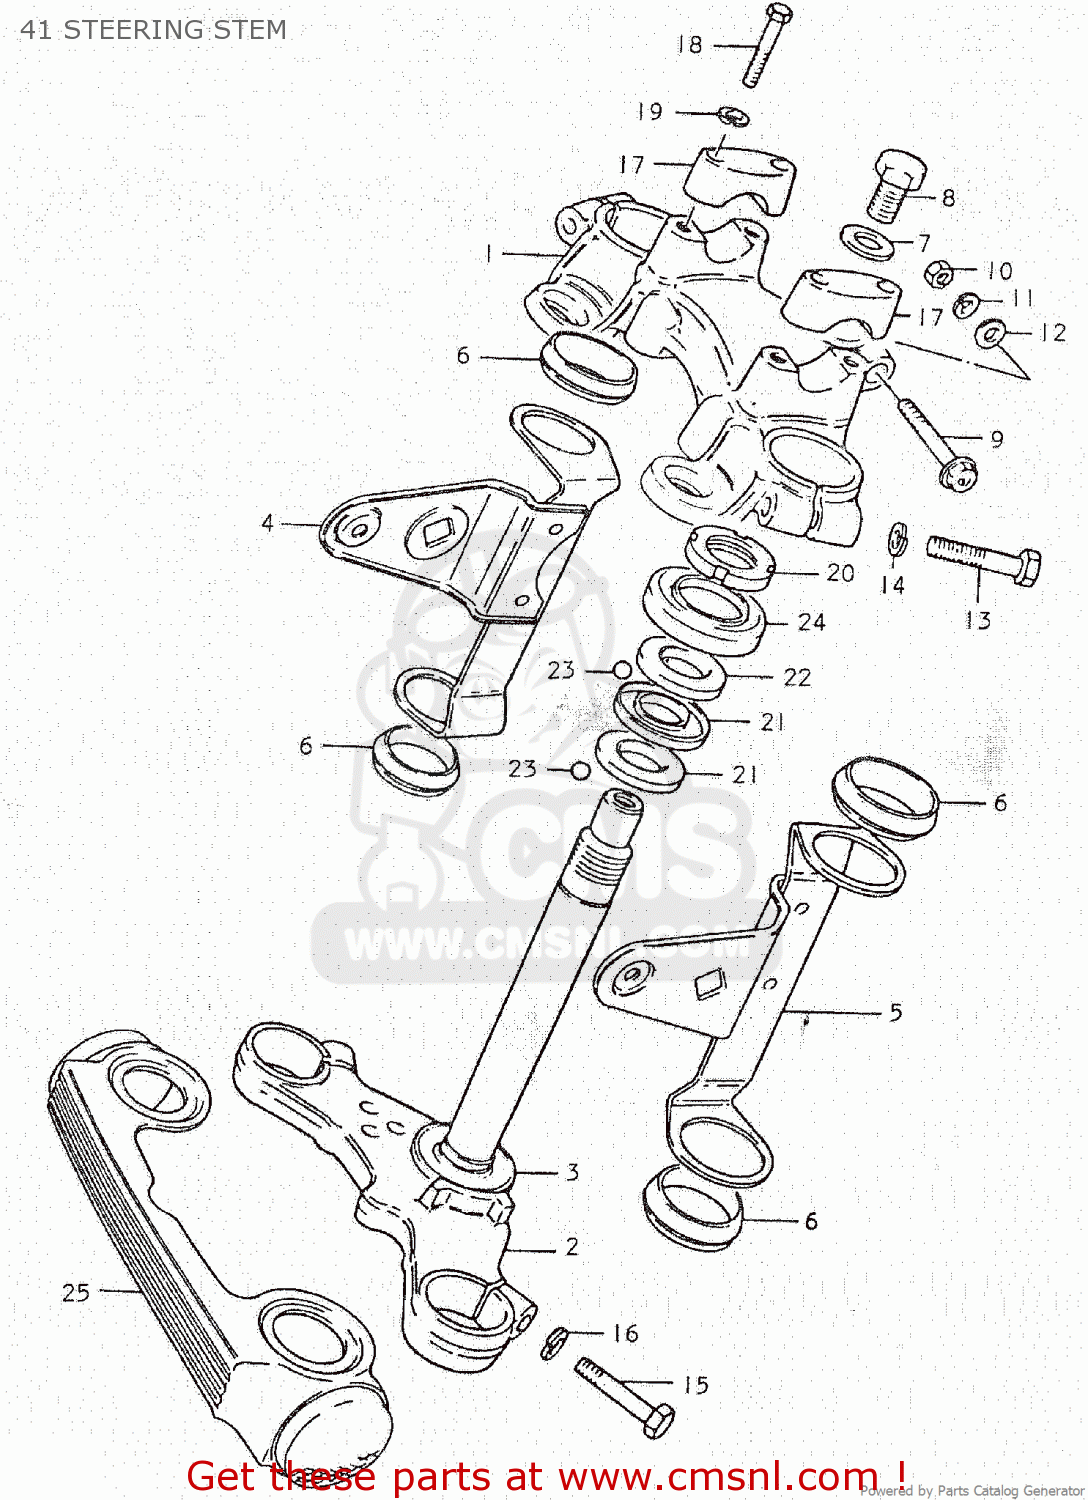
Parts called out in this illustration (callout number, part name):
1	HEAD,STEERING STEM
2	STEM,STEERING
3	RACE,STEERING OUTER LWR
4	BRACKET,HEADLAMP,RIGHT
5	BRACKET,HEADLAMP,LEFT
6	CUSHION,HEADLAMP BRACKET
7	WASHER
8	BOLT(12X20)
9	BOLT
10	NUT
11	LOCK WASHER
12	WASHER
13	BOLT 10X40
14	LOCK WASHER
15	BOLT 10X40
16	LOCK WASHER
17	HOLDER,HANDLE UPR
18	BOLT
19	LOCK WASHER
20	NUT,STEERING STEM(25X44X10)
21	LACE,STEERING INNER LWR
22	LACE,STEERING OUTER UPR
23	BALL
24	DUST SEAL,STEERING UPR
25	COVER,FR FORK
